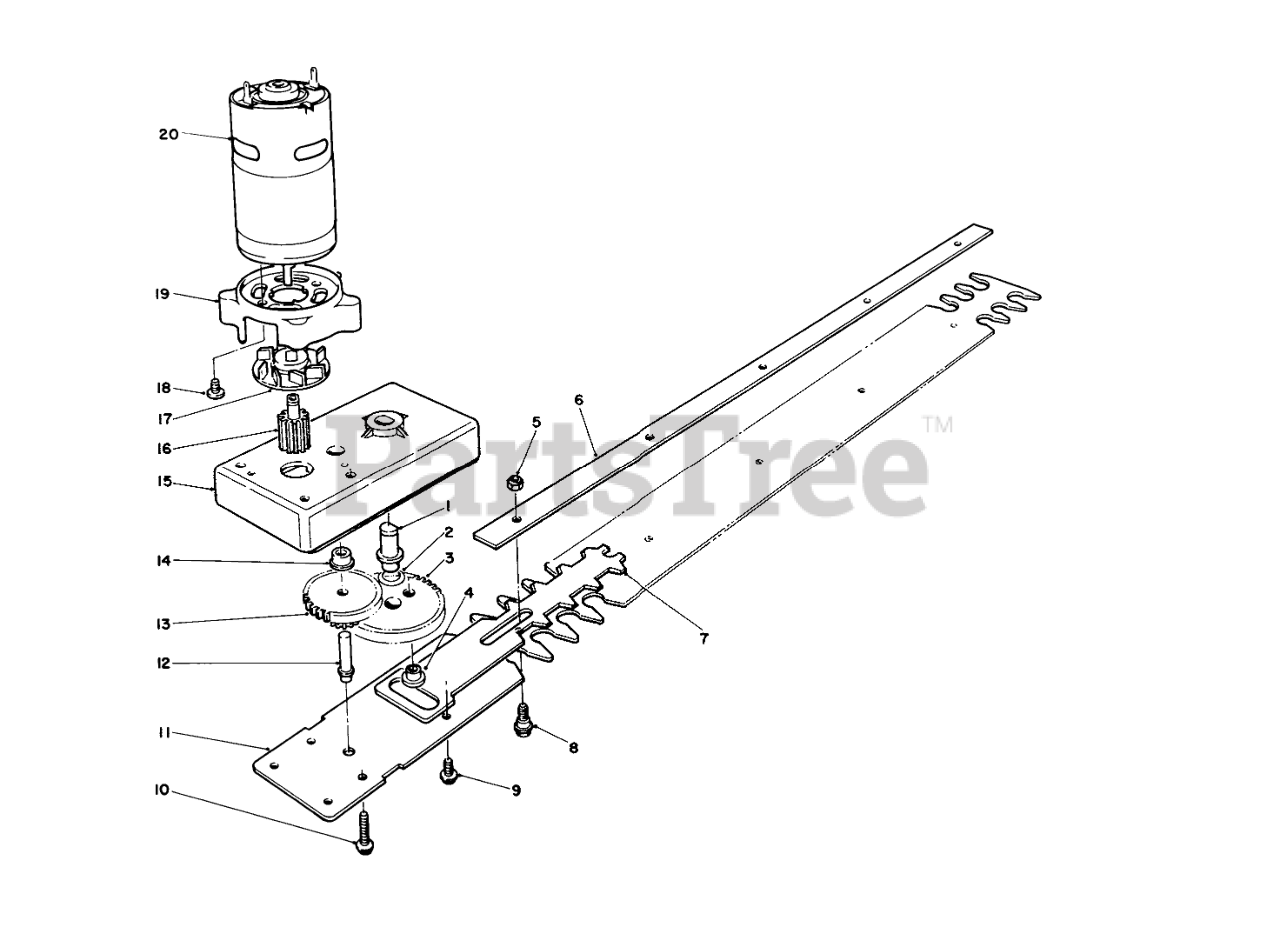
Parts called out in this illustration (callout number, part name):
1	Shaft-Driver
2	WAVE-DRIVER
3	GEAR-DRIVE
4	GEAR BUSHING
5	NUT-LOCK
6	RETAINER BLADE
7	Blade-Cutting
8	BLADE BOLT
9	SCREW-HWHTF
10	SCREW - #8 X 1-1/4
11	Blade-Bottom
12	SHAFT-IDLER
13	GEAR-IDLER
14	Bearing-Idler
15	Housing-Gear Ass-y (Incl. Ref. #1 & 14)
16	Gear-Motor
17	Fan-Motor
18	Screw-Phillips Hd. Pan
19	Support-Motor
20	Motor Assembly (Incl. Ref. #16-19)
